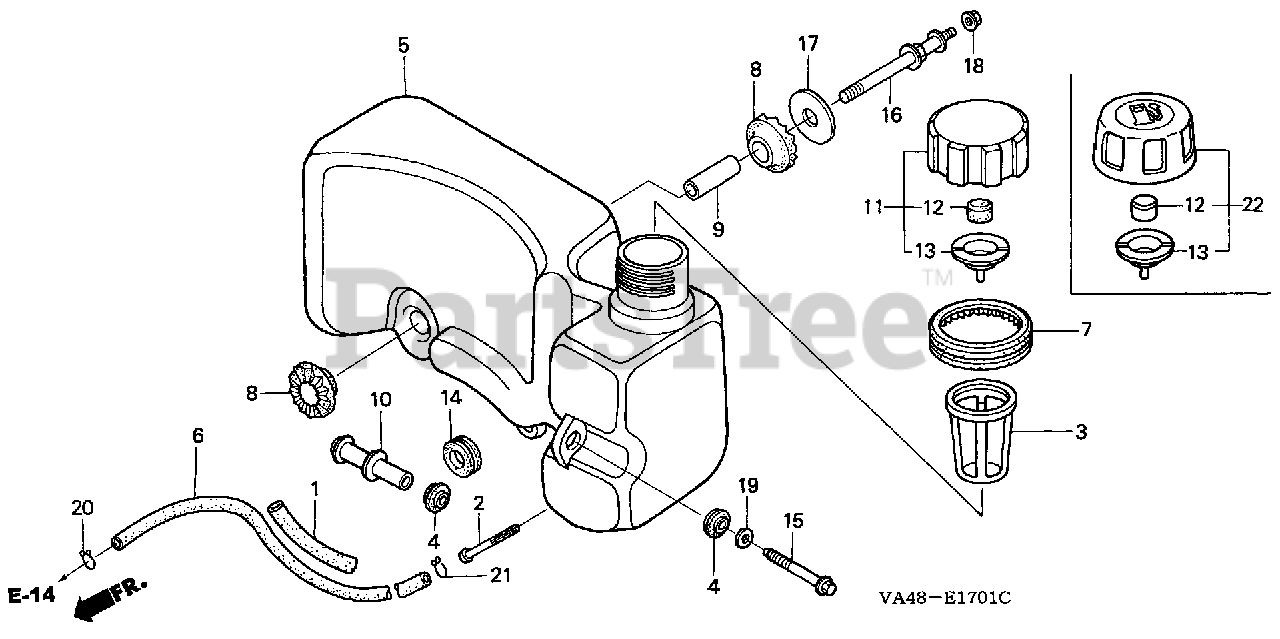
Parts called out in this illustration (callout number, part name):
1	RUBBER, SUPPORTER (107MM)
2	FILTER, FUEL
3	GAUGE, FUEL LEVEL (NOT AVAILABLE)
4	RUBBER, TANK SETTING
5	TANK, FUEL
6	TUBE, FUEL
7	RUBBER, TANK MOUNTING (NOT AVAILABLE)
7	RUBBER, TANK MOUNTING
8	RUBBER B, TANK MOUNTING
9	COLLAR, TANK SETTING
10	COLLAR, TANK
11	CAP ASSY., FUEL TANK
12	SPONGE, FUEL CAP BREATHER
13	GASKET, FUEL CAP
14	CUSHION, RR. FENDER
15	BOLT, FLANGE (6X50)
16	BOLT, TANK STAY
17	WASHER, TANK MOUNTING
18	NUT, FLANGE (6MM)
19	WASHER, PLAIN (6MM)
20	CLIP, TUBE (B8)
21	CLIP, TUBE (C11)
22	CAP ASSY., FUEL TANK
